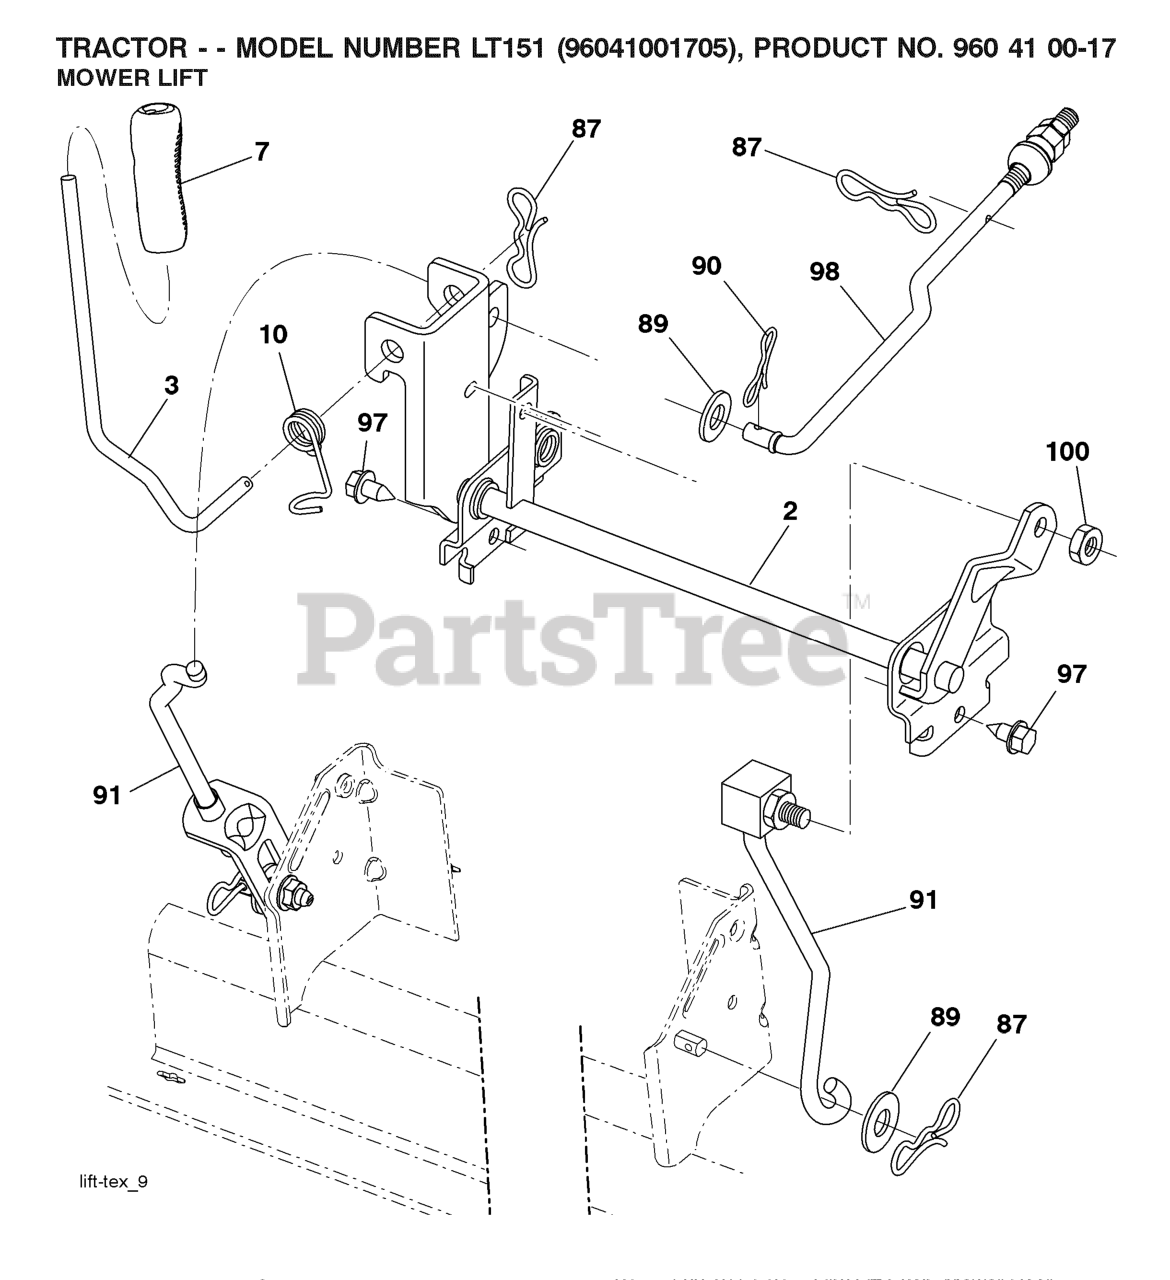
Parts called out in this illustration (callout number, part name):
2	SHAFT.ASM.LIFT.CROSS.H
3	LEVER.LIFT.HANDLE.LT
7	GRIP.HANDLE.LIFT.PVC.BLACK
10	SPRING.TORSION.LIFT.HANDLE
87	PIN.COTTER.7/16.BOW TI.
88	SPRING.LIFT.ASSIST
89	WASHER.CLEAR.ZINC
90	PIN.COTTER.5/16.BOW TI
91	LINK.ASM.LIFT.REAR
97	SCREW, 3/8-16X3/4
98	LINK.ASM.SUSP.FRONT.MW
100	LOCKNUT
